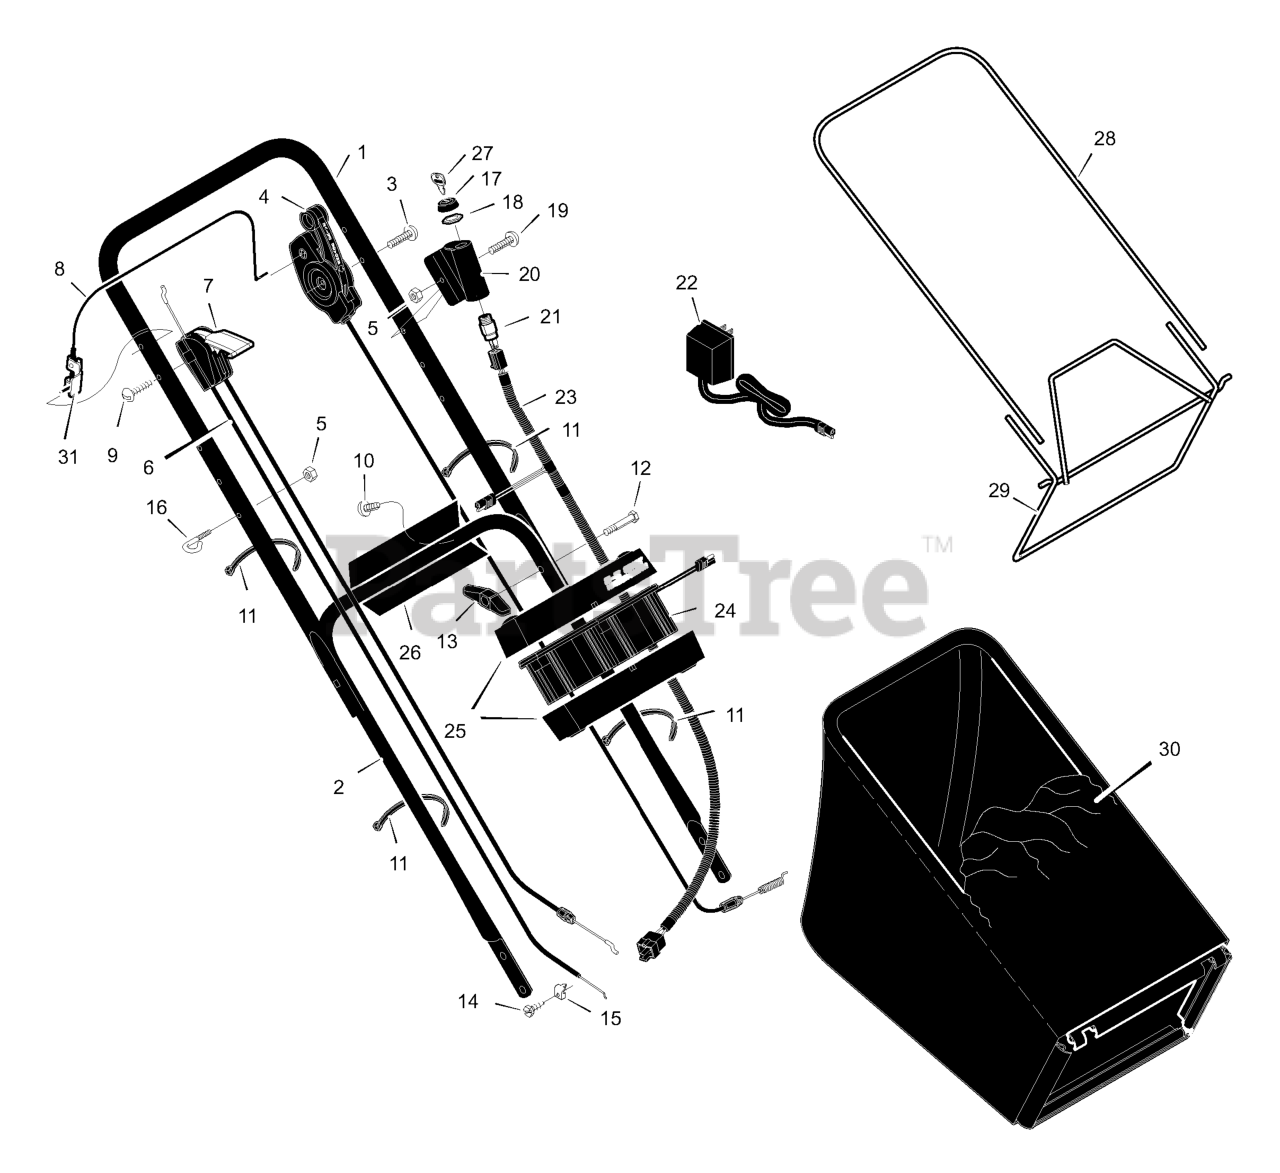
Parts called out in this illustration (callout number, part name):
1	Handle, Upper (Black)
2	Handle, Lower (Black)
4	Control, Drive
5	Locknut
6	Cable, Stop
7	Throttle Control
8	Engine Stop Lever
11	Fastener, Cable
13	Knob
16	GUIDE, ROPE
17	Cap
18	Nut
20	Cover, Ignition
21	Switch Ignition & Key
22	Charger, Battery
23	Harness, Wiring
24	Battery
25	Case, Battery
26	Bracket, Battery
27	Key, Ignition
28	Frame, Top
29	Frame Assembly
30	Bag, Cloth
31	Bracket, Stop Lever
